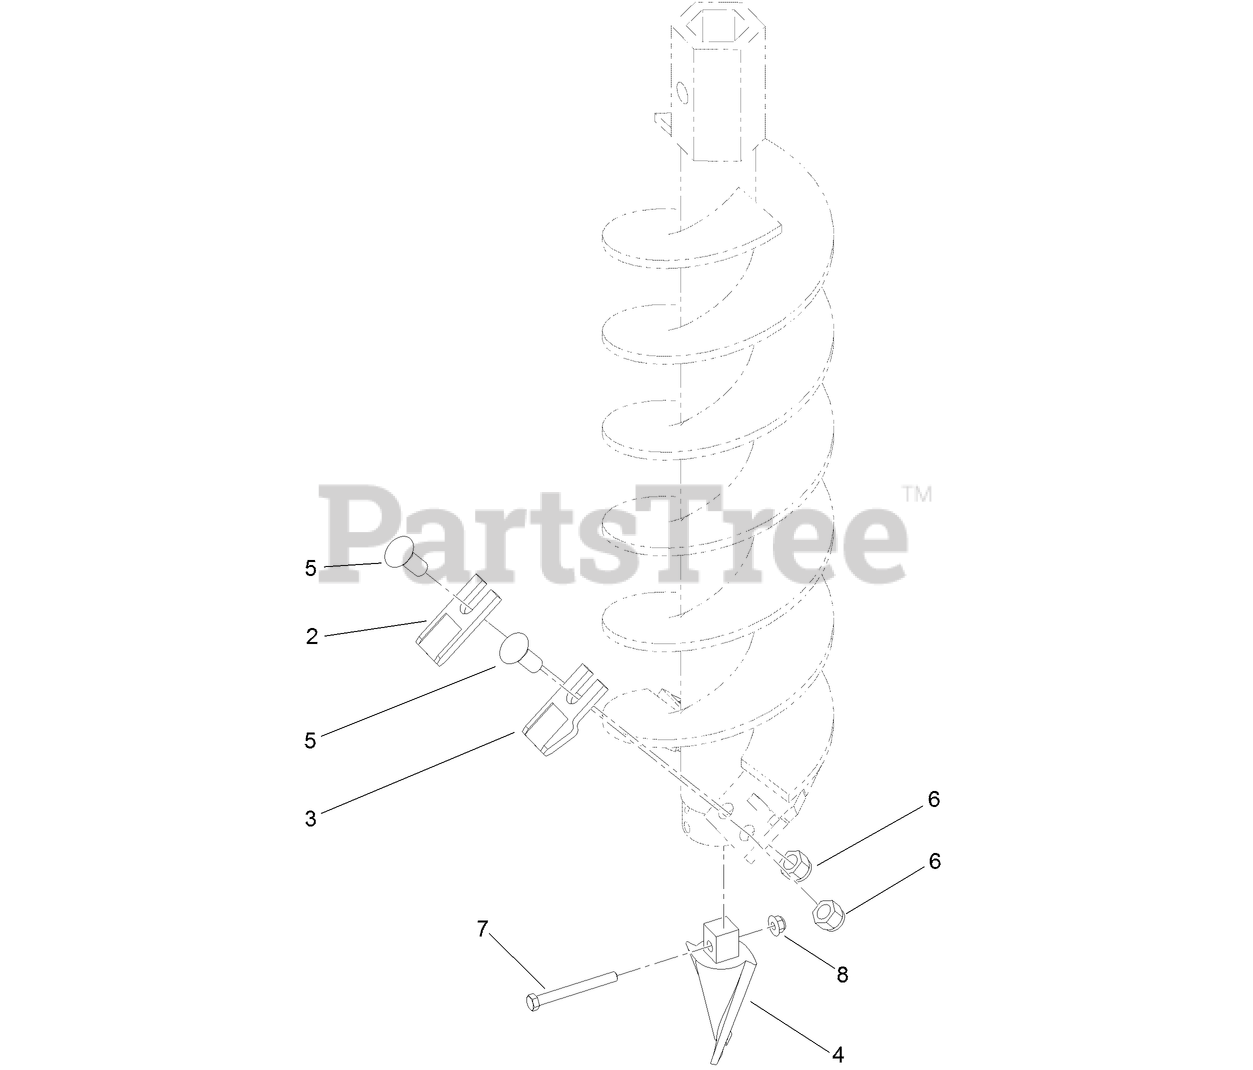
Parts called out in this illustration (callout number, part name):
2	TOOTH-AUGER, WISDOM (INSIDE)
3	TOOTH-AUGER, WISDOM (OUTER)
4	TOOTH-FISHTAIL, STANDARD
5	SCREW-CARRIAGE
6	NUT-LOCK, NI
7	SCREW-HH
8	NUT-HF, NI
